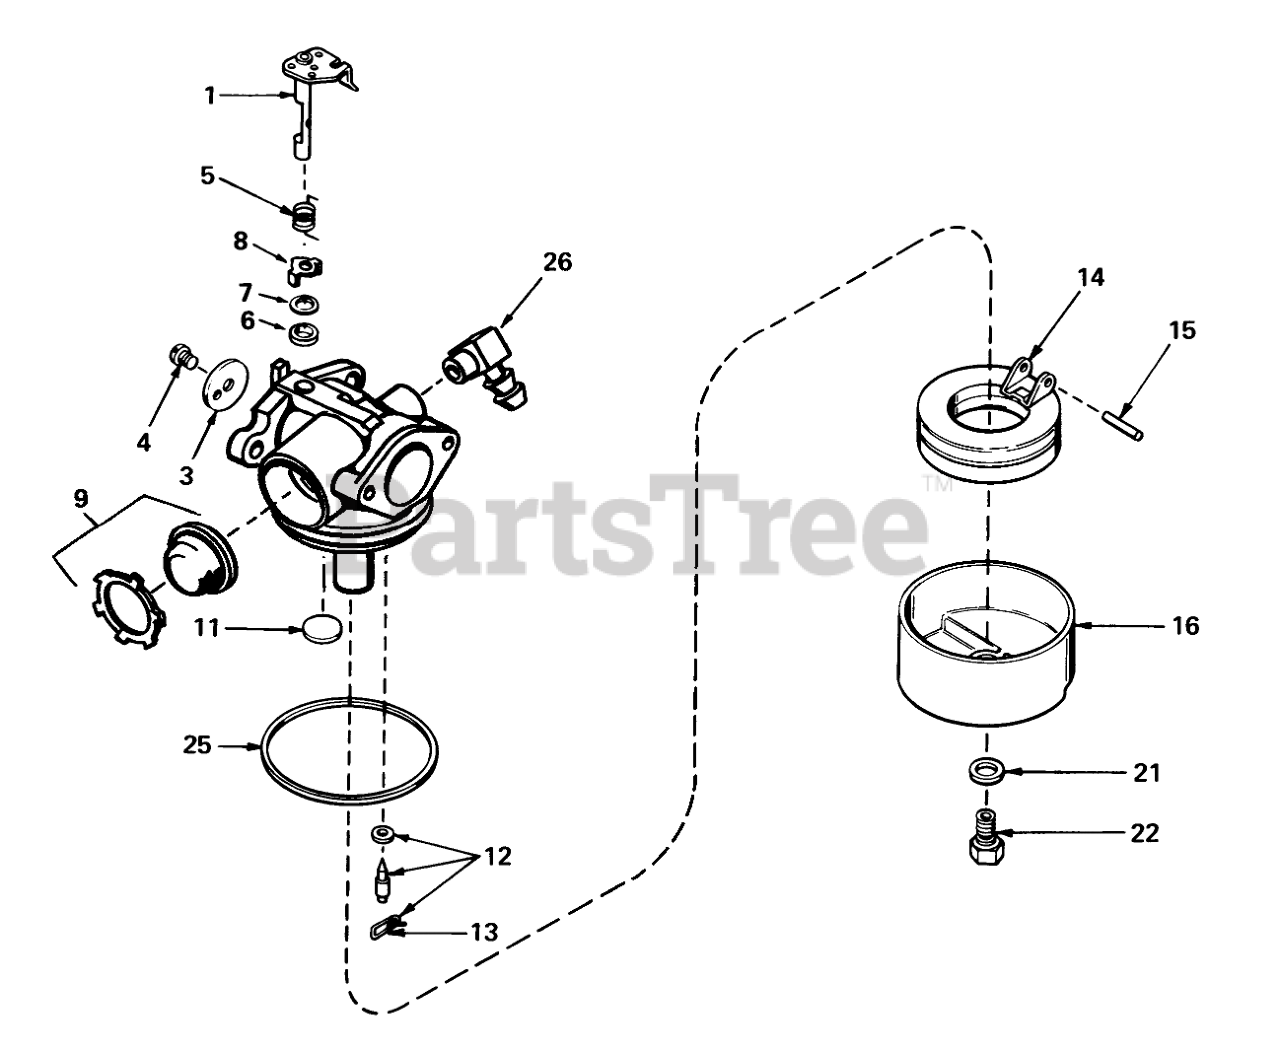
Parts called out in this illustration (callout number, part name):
1	Throttle Shaft and Lever ASM
3	Throttle-Shutter
4	Screw-Shutter
5	Spring, Return
6	Seal-Dust
7	Washer-Seal, Dust
8	Retainer, Seal
9	Primer Assy.
11	Plug-Welch, Atmospheric Vent
12	Inlet Needle, Seat & Clip Assy. (Incl. Ref. #13)
13	Clip-Spring
14	Float
15	Shaft-Float
16	Bowl Float
21	Gasket-Bowl
22	Nut-Float Bowl
25	O Ring-Bowl, Float
26	Fitting-Fuel
